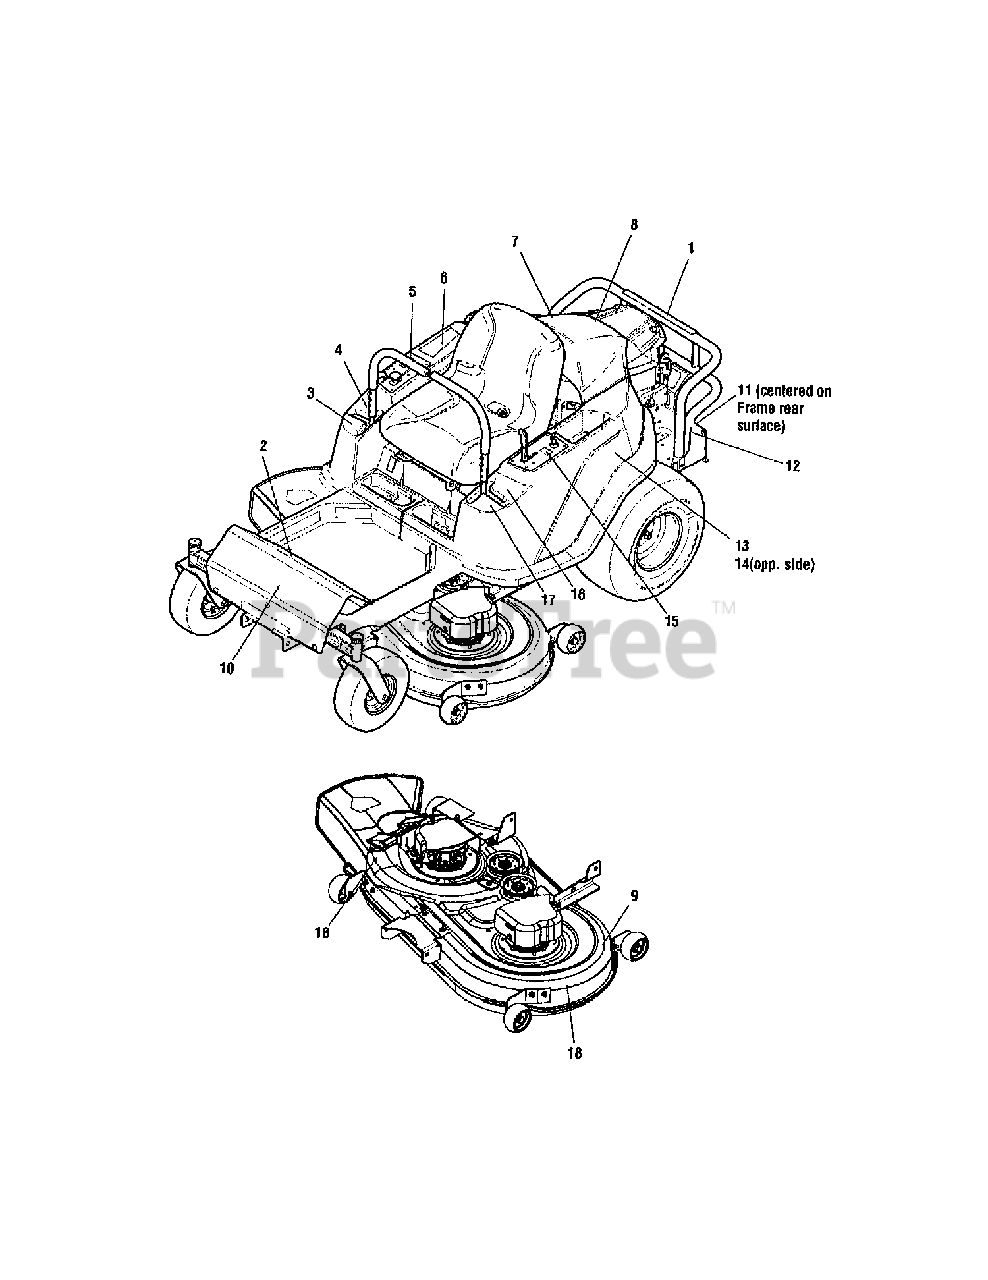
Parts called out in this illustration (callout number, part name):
1	DECAL, Model, SNAPPER, 21HP
2	DECAL, Instructional
3	DECAL, Handle, Ground Speed, RH
4	DECAL, Warning, English, RH
5	DECAL, Control Panel, RH
6	DECAL, Danger, Hazards, English
7	DECAL, Release, Transaxle
8	DECAL, Caution, Rotating Screen
9	DECAL, 42" Deck
10	DECAL, Logo, SNAPPER 7.88"
11	DECAL, Weight Limitation
12	DECAL, Warning, Burn Hazard
13	DECAL, LH Fender, SNAPPER
14	DECAL, RH Fender, SNAPPER
15	DECAL, Control Panel, LH
16	DECAL, Warning, English, LH
17	DECAL, Handle, Ground Speed, LH
18	DECAL, Danger Do Not Operate w/o Deflector
